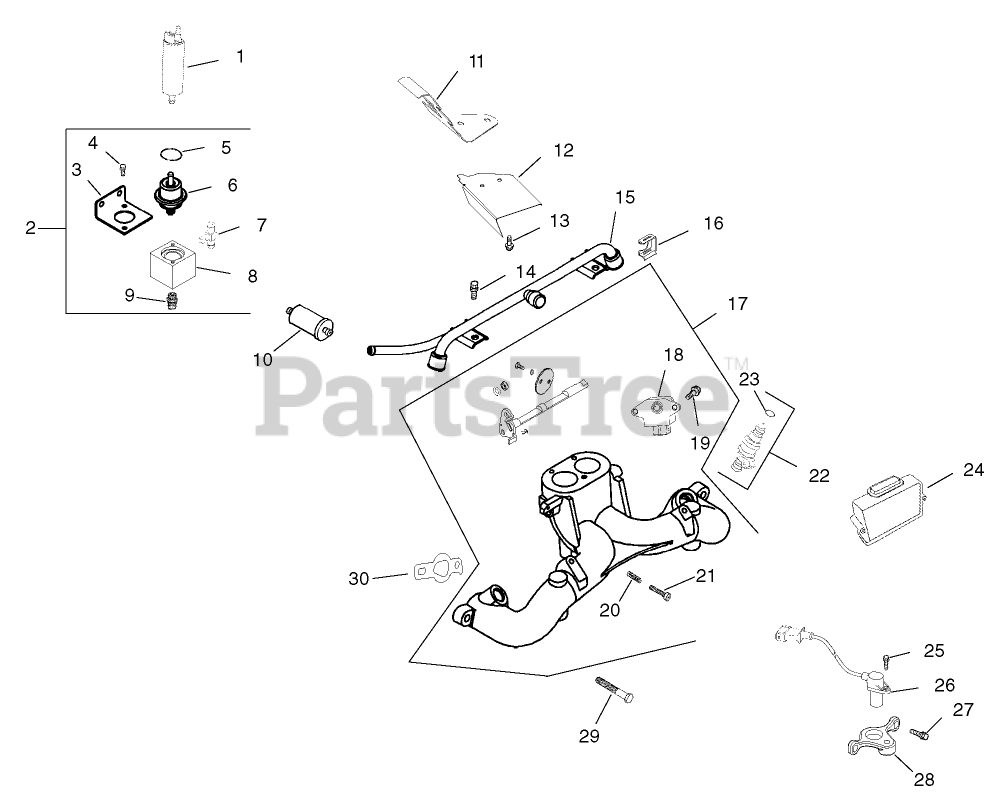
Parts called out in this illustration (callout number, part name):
1	Pump assembly, fuel (Includes filter 24 05006-S)
2	Regulator assembly, pressure (Includes 3-9)
3	Bracket-Regulator,Horizontal
4	Screw-HH
5	O-Ring
6	Regulator-Pressure
7	Fitting-Tee
8	Housing-Regulator,Horizontal
9	Connector-Hose, Straight
10	Filter-Fuel
11	Baffle-Valley
12	Deflector-Air
13	SCREW-HHFTF (M5X.80X10)
14	Screw-HF (M6x1.0x12)
15	Rail-Fuel
16	Clip-Injector, Fuel
17	Manifold assembly, intake (Includes 18-21)
18	Sensor-Position,Throttle
19	Screw-Head, Pan
20	Spring-Control, Speed
21	Screw-HH
22	Injector, fuel (2)(Includes 23)
23	O-RING
24	Control unit, electronic (ECU)
25	Screw-HF
26	Sensor-Speed, Engine
27	SCREW-FLANGE, THREAD FORMING (M5X0.8X16)
28	Bracket-Sensor,Speed
29	Screw-HF
30	Gasket-Manifold, Intake
